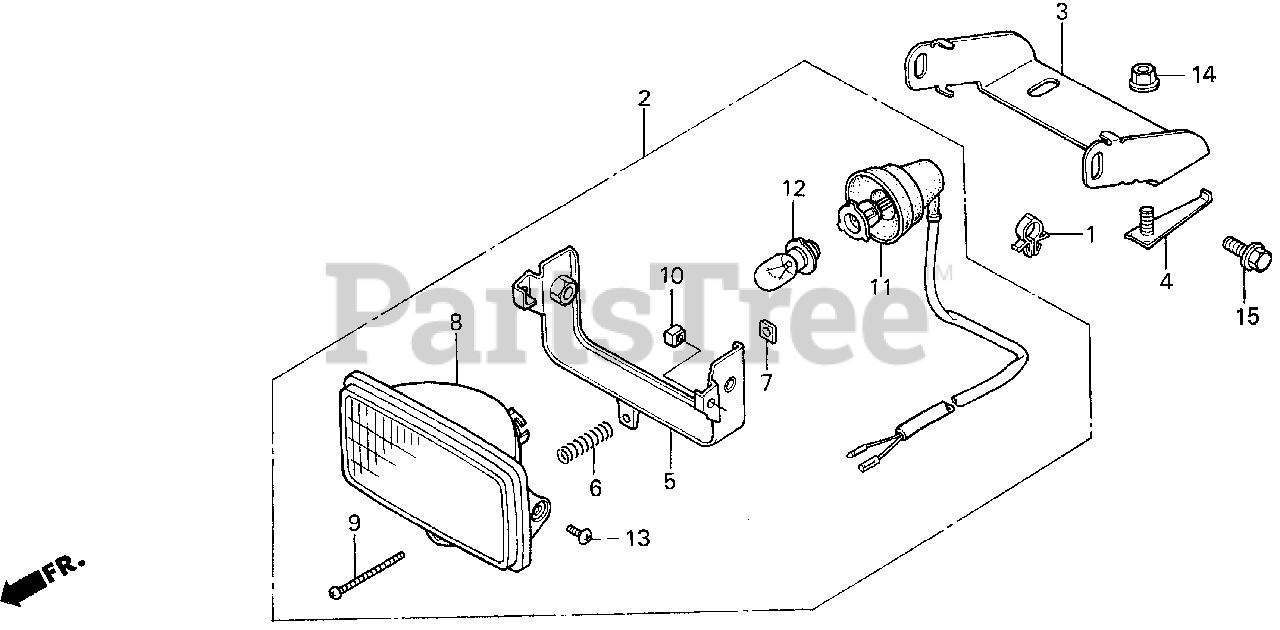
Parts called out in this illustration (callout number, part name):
1	CLIP, IGNITION WIRE (8MM)
2	HEADLIGHT ASSY.
3	BRACKET, HEADLIGHT
4	BOLT, HEADLIGHT SPECIAL
6	SPRING, BEAM ADJUSTING
7	NUT, HEADLIGHT BEAM ADJUSTING
8	HEADLIGHT UNIT
9	SCREW, BEAM ADJUSTING
10	NUT, UNIT HOLDER
11	SOCKET ASSY., HEADLIGHT
12	BULB (12V25/25W) (STANLEY)
13	SCREW, PAN (5X10)
14	NUT, FLANGE (8MM)
15	BOLT, FLANGE (8X12)
